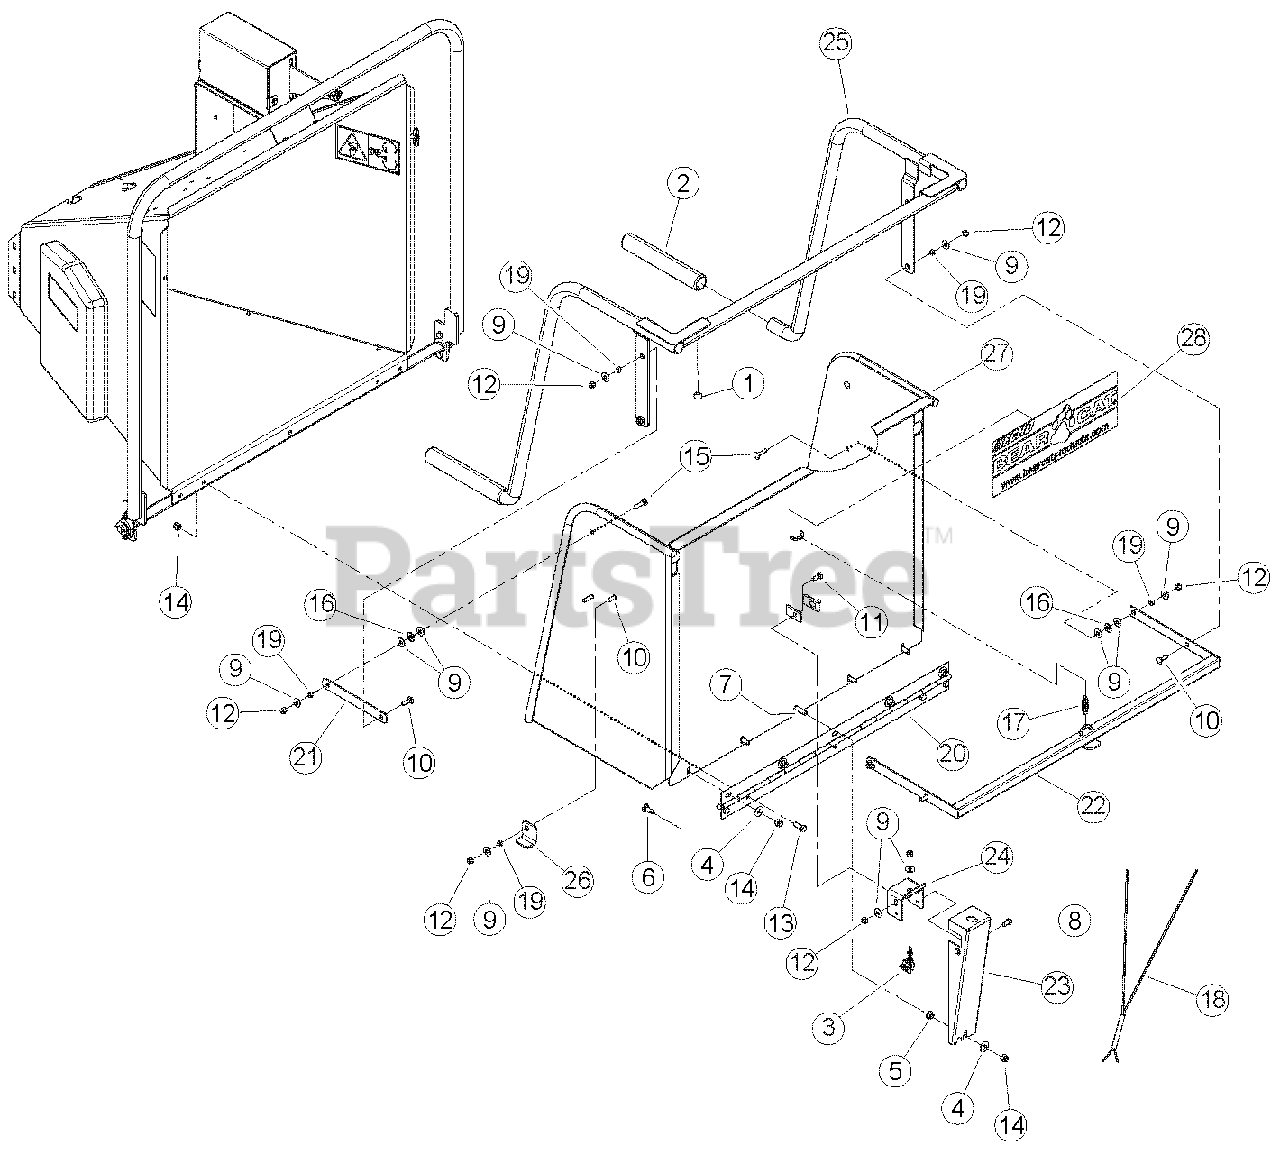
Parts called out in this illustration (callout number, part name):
1	BUMPER, RUBBER
2	GRIP, 1.219 X 10.00
4	WASHER, 3/8 FLAT ZP
5	NUT, 3/8 SERR FLANGE ZP
6	BOLT, 3/8 X 1 CRG GR5 NC ZP
7	BOLT, 3/8 X 1-1/2 CRG GR5 NC ZP
8	SCREW, 11/32 X 7/8 HWH AB THREAD ZP
9	WASHER, 5/16 FLAT ZP
10	BOLT, 5/16 X 1 CRG GR5 ZP
11	BOLT, 5/16 X 7/8 CRG GR5 NC ZP
12	NUT, 5/16 NE NYLOCK ZP
13	BOLT, 3/8 X 1-1/4 HEX HD GR5 ZP
14	NUT, 3/8 NE NYLOCK ZP
15	BOLT, 5/16 X 1-1/4 CRG GR5 ZP
16	WASHER, 5/16 ID. X 7/8 OD. NYLON FLAT
17	SPRING 1/2 X 2.00 LG,ZP
18	HARNESS, SAFETY BAR
19	SPACER, IDLER PIVOT
20	HINGE, EXTENSION TRAY
21	LINK, PARALLEL
22	WELDMENT, KNEEBAR PIVOT
23	SHIELD, KNEEBAR SWITCH
24	BRACKET, SWITCH
25	WELDMENT, KNEEBAR
26	LOCK, SAFETY BAR
27	ASSEMBLY, EXT. TRAY, SERVICE PART
28	DECAL, BEARCAT WEB
